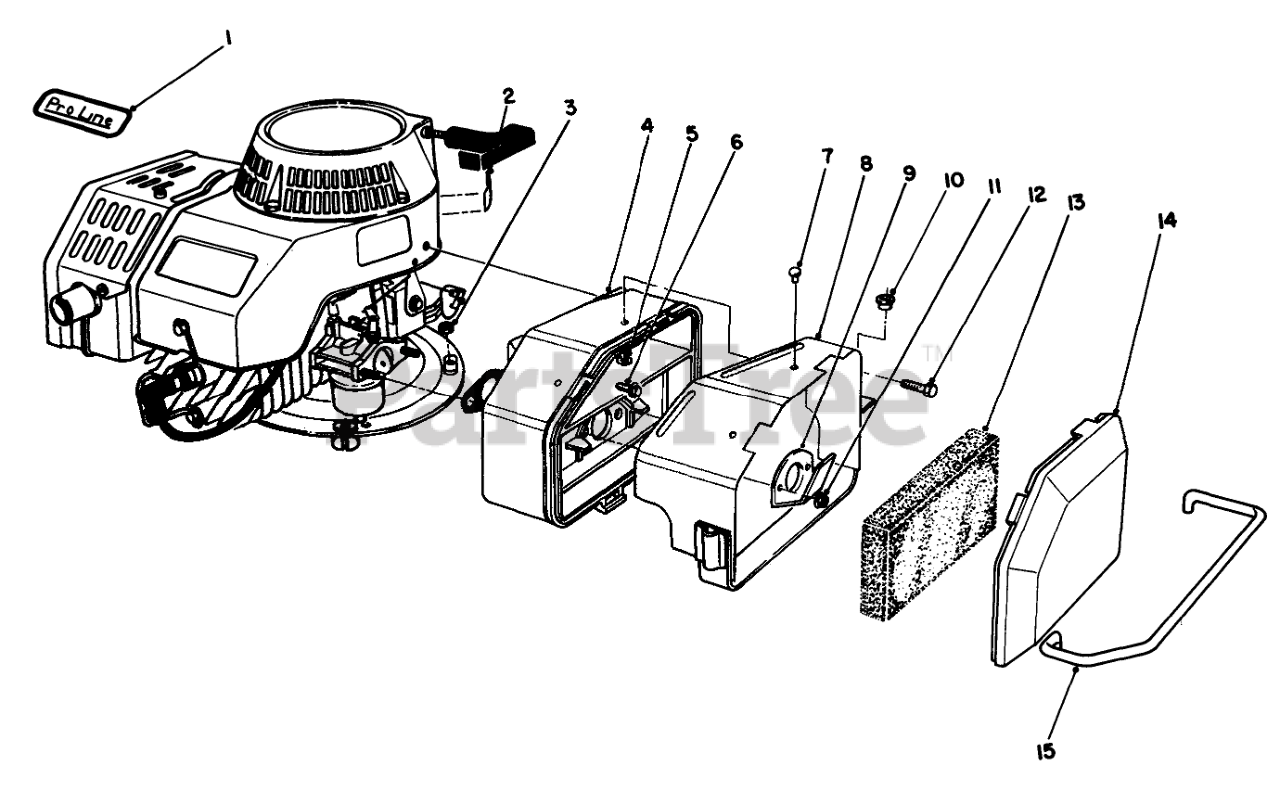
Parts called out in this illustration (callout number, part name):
1	DECAL - PROLINE
2	DECAL - FUEL
3	NUT-JAM
4	Air Cleaner Assembly (Incl. Ref. #5, 7 & 8)
5	WASHER-FLAT
6	HEX FL HD M.6X1.0X25MM
7	RIVET-POP
8	AIR CLEANER COVER WA
9	SPIT BACK DEFLECTOR
10	5/16 ID BSHG
11	NUT-LOCK
12	SCREW-HHF
13	FILTER
14	AIR CLEANER COVER
15	AIR CLEANER GUARD
